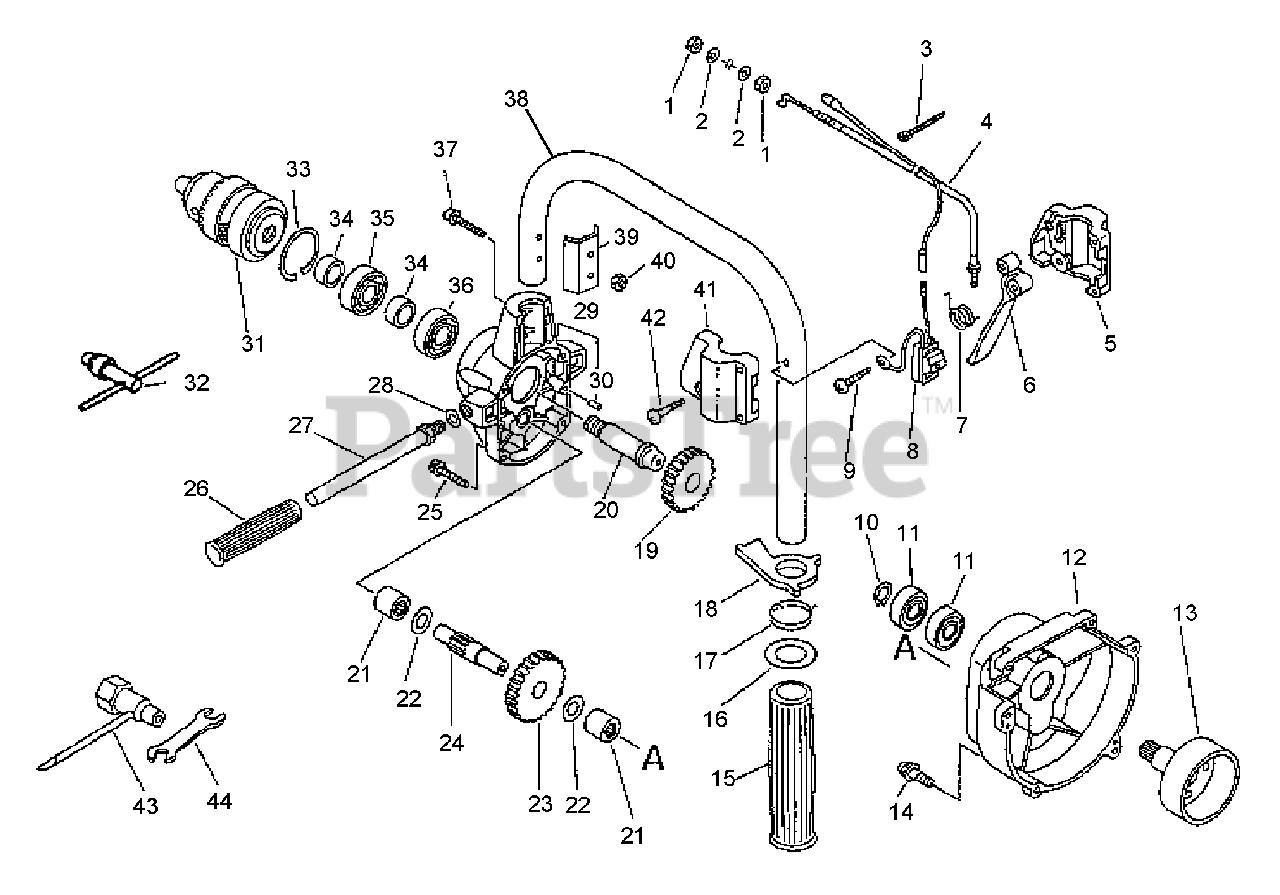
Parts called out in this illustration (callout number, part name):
2	WASHER - 6
3	TIE, CABLE
4	CABLE, THROTTLE
5	BRACKET, THROTTLE CONTROL - RIGHT
6	TRIGGER, THROTTLE
7	SPRING, TRIGGER
8	IGNITION SWITCH ASSY
9	SCREW - 4X30
10	RING, RETAINING - 12
11	BEARING, BALL - 6001C3
12	CASE, FAN
13	DRUM, CLUTCH
14	SCREW - 4X16
15	GRIP, HANDLE - LEFT
16	SPACER
17	SPRING, LOCKOUT LEVER
18	LEVER, TRIGGER LOCKOUT
19	GEAR - SPUR
20	GEAR - SHAFT
21	BEARING, NEEDLE
23	GEAR - SPUR -- 12 TOOTH
24	GEAR - SHAFT
25	SCREW - 4X25
26	GRIP - FRONT
27	HANDLE - FRONT
28	WASHER - 10
29	CASE, GEAR
30	PIN - LOCATING
32	KEY, CHUCK
33	RING, RETAINING - 32
35	BEARING, BALL - 6002
36	BEARING, BALL - 6002
37	SCREW - 5X35
38	HANDLE ASSY - REAR
39	PLATE, HANDLE
40	LOCKNUT - 5
41	BRACKET, THROTTLE CONTROL - LEFT
42	SCREW - 4X25
43	T-WRENCH - 10X19mm
44	SPANNER - 17X19mm
